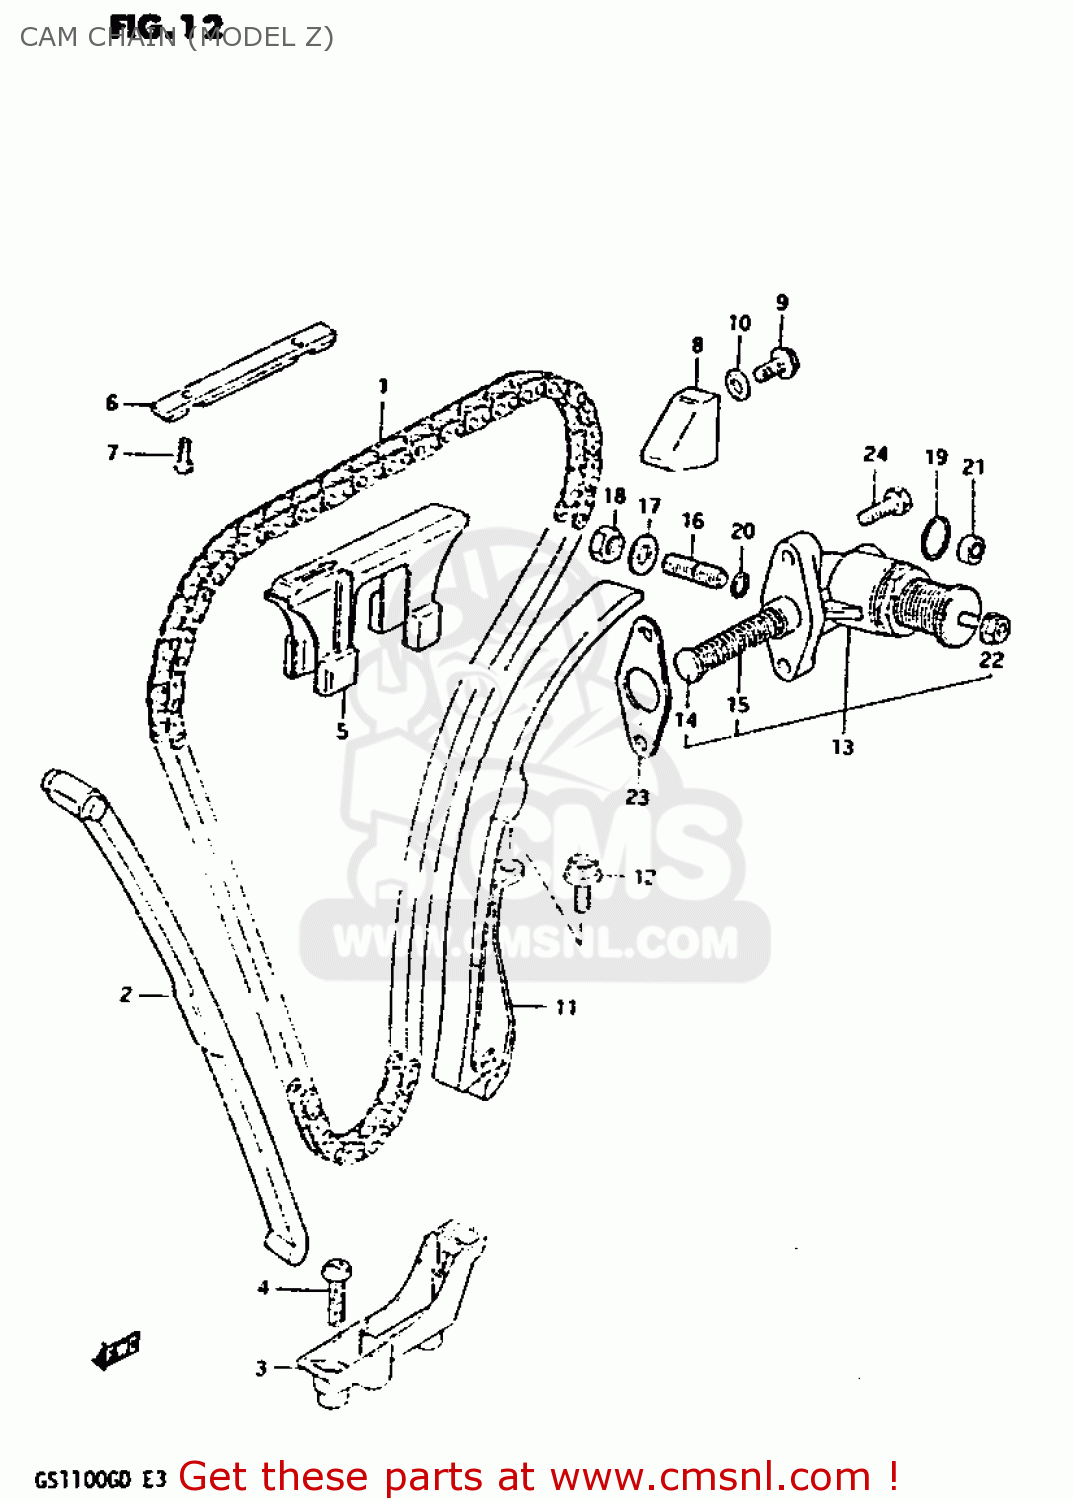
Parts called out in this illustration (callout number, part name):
1	CHAIN,CAMSHAFT DRIVE
2	GUIDE,CAM CHAIN NO.1
3	HOLDER,CAM CHAIN GUIDE
4	SCREW
5	GUIDE,CAM CHAIN NO.2
6	GUIDE,CAM CHAIN
7	SCREW
8	GUIDE,CAM CHAIN
9	BOLT 6X12
10	GASKET(5.8X13X1.2) (NAS)
11	TENSIONER,CAM CHAIN
12	BOLT 8X16
13	ADJUSTER,CAM CHAIN TENSIONER
14	ROD,PUSH
15	SPRING
16	SCREW
17	WASHER
18	NUT
19	O RING(D:2.4,ID:20.8)
20	O RING(D:1.9,ID:5.7)
21	SEAL,OIL(10X16X4)
22	NUT
23	GASKET,TENSIONER ADJUSTER (MCA)
24	SCREW (6X25)
